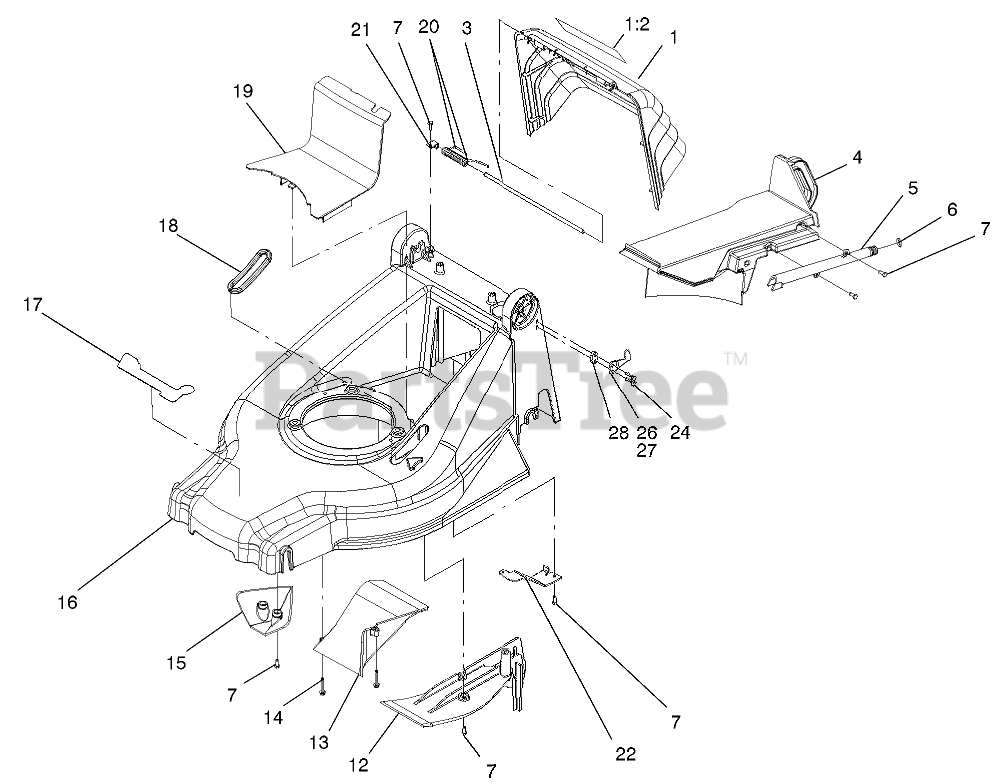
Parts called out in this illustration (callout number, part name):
1	DOOR ASM
1:2	DECAL-DANGER
3	ROD-PIVOT
4	PLUG-KICKER, RECYCLER
5	FITTING-WASHOUT
6	O-RING
7	SCREW-TAPTITE
12	COVER-KICKER, REAR
13	RAMP-DISCHARGE
14	SCREW-HWH
15	KICKER-FRONT
16	Deck
17	DECAL-RECYCLER
18	BOOT-HOC
19	COVER-BELT
20	SPRING-TORSION
21	CLAMP
22	BRACKET-DECK
24	SCREW-HWH
26	Hook-Left
27	Hook-Right
28	Spacer
